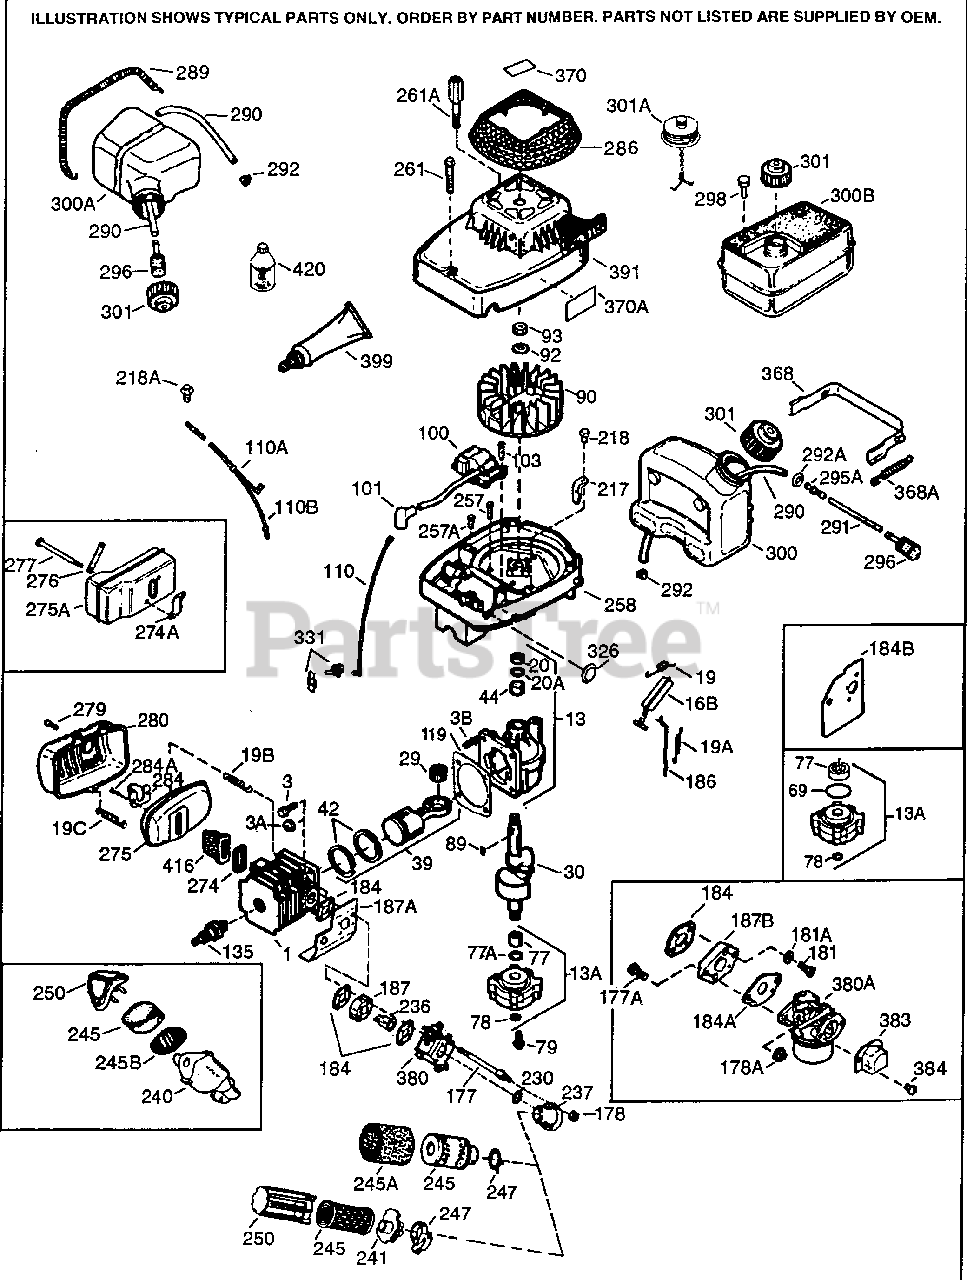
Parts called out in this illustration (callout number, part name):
1	"Cylinder (Incl. 119, 184, 187 & 187A)
3	Screw, Torx T-30, 1/4-20 x 43/64"
13	Crankcase Ass'y. (Incl. 20 & 44)
13A	Crankcase Cover Ass'y.(Incl. 77 & 78)
16B	Air Vane
19	Governor Spring
19A	Backlash Spring
19B	Muffler Spring
19C	Heat Shield Spring
20	Oil Seal
30	Crankshaft
39	Piston & Rod Ass'y. (Incl. 42)
42	Ring Set
44	Cartridge Bearing
77	Cartridge Bearing
78	Oil Seal
79	Screw, 1/4-20 x 3/4"
89	Flywheel Key
90	Flywheel
92	Belleville Washer
93	Flywheel Nut
100	Solid State Ignition (Incl. 101)
101	Spark Plug Cover
103	Screw, Torx T-15, 10-24 x 1"
110	Ground Wire
135	Resistor Spark Plug (RCJ8Y)
177	Carburetor Mounting Stud
178	Lock Nut, 10-24
184	Carburetor Gasket
186	Governor Link
187A	Air Baffle
217	Control Lever
218	Screw, 8-32 x 1/2"
230	"O" Ring
237	Air Cleaner Adapter
245	Air Filter
247	Air Cleaner Clamp
257	Screw, 10-24 x 1/2"
258	Blower Housing Base
261	Screw, 8-32 x 1-9/16"
274	Exhaust Gasket
275	Muffler
279	Screw, 8-32 x 1/2"
280	Heat Shield
286	Starter Screen
290	Fuel Line
291	Fuel Line
292	Fuel Line Clamp
295A	Fuel Line Fitting
296	Fuel Filter
300	Fuel Tank Incl. 291, 292A, 295A & 296
301	Fuel Cap
326	Blower Housing Plug
331	Toggle Switch
368	Fuel Tank Strap
368A	Fuel Tank Strap Spring
370	Instruction Decal
380	Carburetor (Inc. 184)
391	Rewind Starter & Housing Ass'y.
399	Gasket Eliminator (Loctite 515)
416	Spark Arrestor Kit
420	2-Cycle Oil with Fuel Stabilizer - 8 oz.
